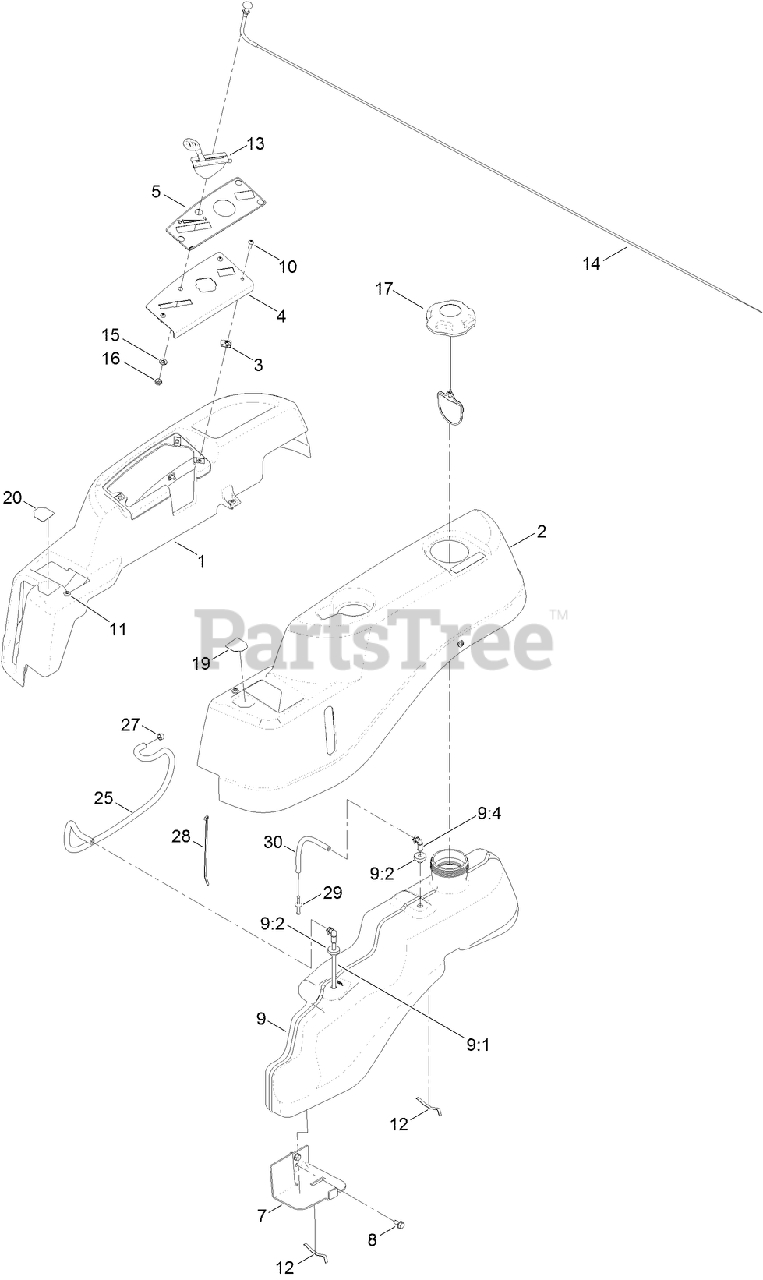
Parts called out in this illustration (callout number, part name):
1	POD-RH
4	PLATE-CONTROL
5	DECAL-PANEL, CONTROL
7	SUPPORT-TANK, FRONT
8	SCREW-HWHTF
9	FUEL TANK ASM
9:1	CONNECTOR-ELBOW, 90 DEG
9:2	BUSHING
9:4	FITTING-PLASTIC
10	SCREW-PRH
11	SCREW-SHOULDER
12	SPRING
13	CABLE-THROTTLE
14	CABLE-CHOKE
15	WASHER-LOCK
16	NUT-HJ
19	DECAL-LEVER, CONTROL (LH)
20	DECAL-LEVER, CONTROL (RH)
25	HOSE-FUEL
27	CLAMP-HOSE
28	TIE-CABLE
29	ADAPTOR-ORIFICE
30	HOSE-FUEL
